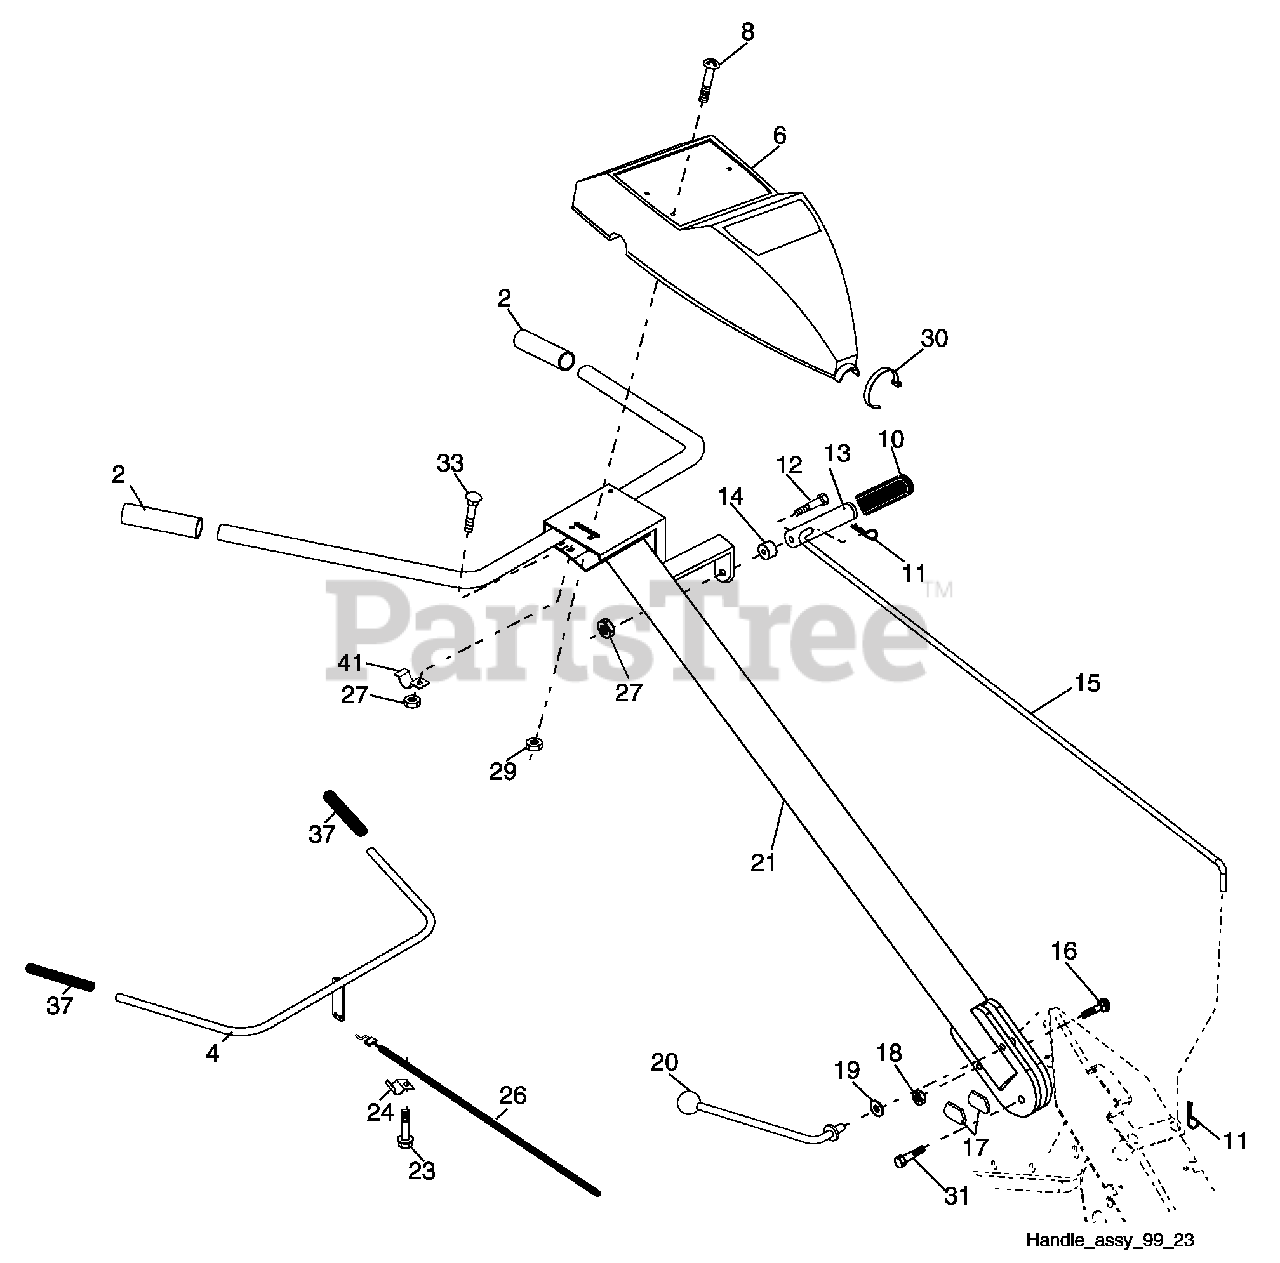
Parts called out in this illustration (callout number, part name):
2	Grip, Handle
4	Bar Assembly, Control
6	Panel, Control
8	Screw, Truss Hd. #10-24 unc x 1/2
10	Grip, Handle
11	Clip, Hairpin
12	Bolt, Shoulder
13	Handle, Shift
14	Grommet, Rubber
15	Rod, Shift
16	Bolt, Carriage 3/8-16 x 1 Gr. 5
17	Lock, Handle
18	Nut, Crownlock 3/8-16 unc
19	Washer 13/32 x 1 x 11 Ga.
20	Lever, Lock, Handle
21	Handle
23	Screw, Hex Washer SLT#10-24 x .50
26	Cable, Clutch
27	Nut, Hex Flange 1/4-20 unc
29	Nut, Keps #10-24 unc
30	Tie, Cable
31	Bolt, Pivot
33	Bolt, Carriage 1/4-20 unc x 1/2
37	Grip, Bar, Control
41	Clamp, Bar, Control
